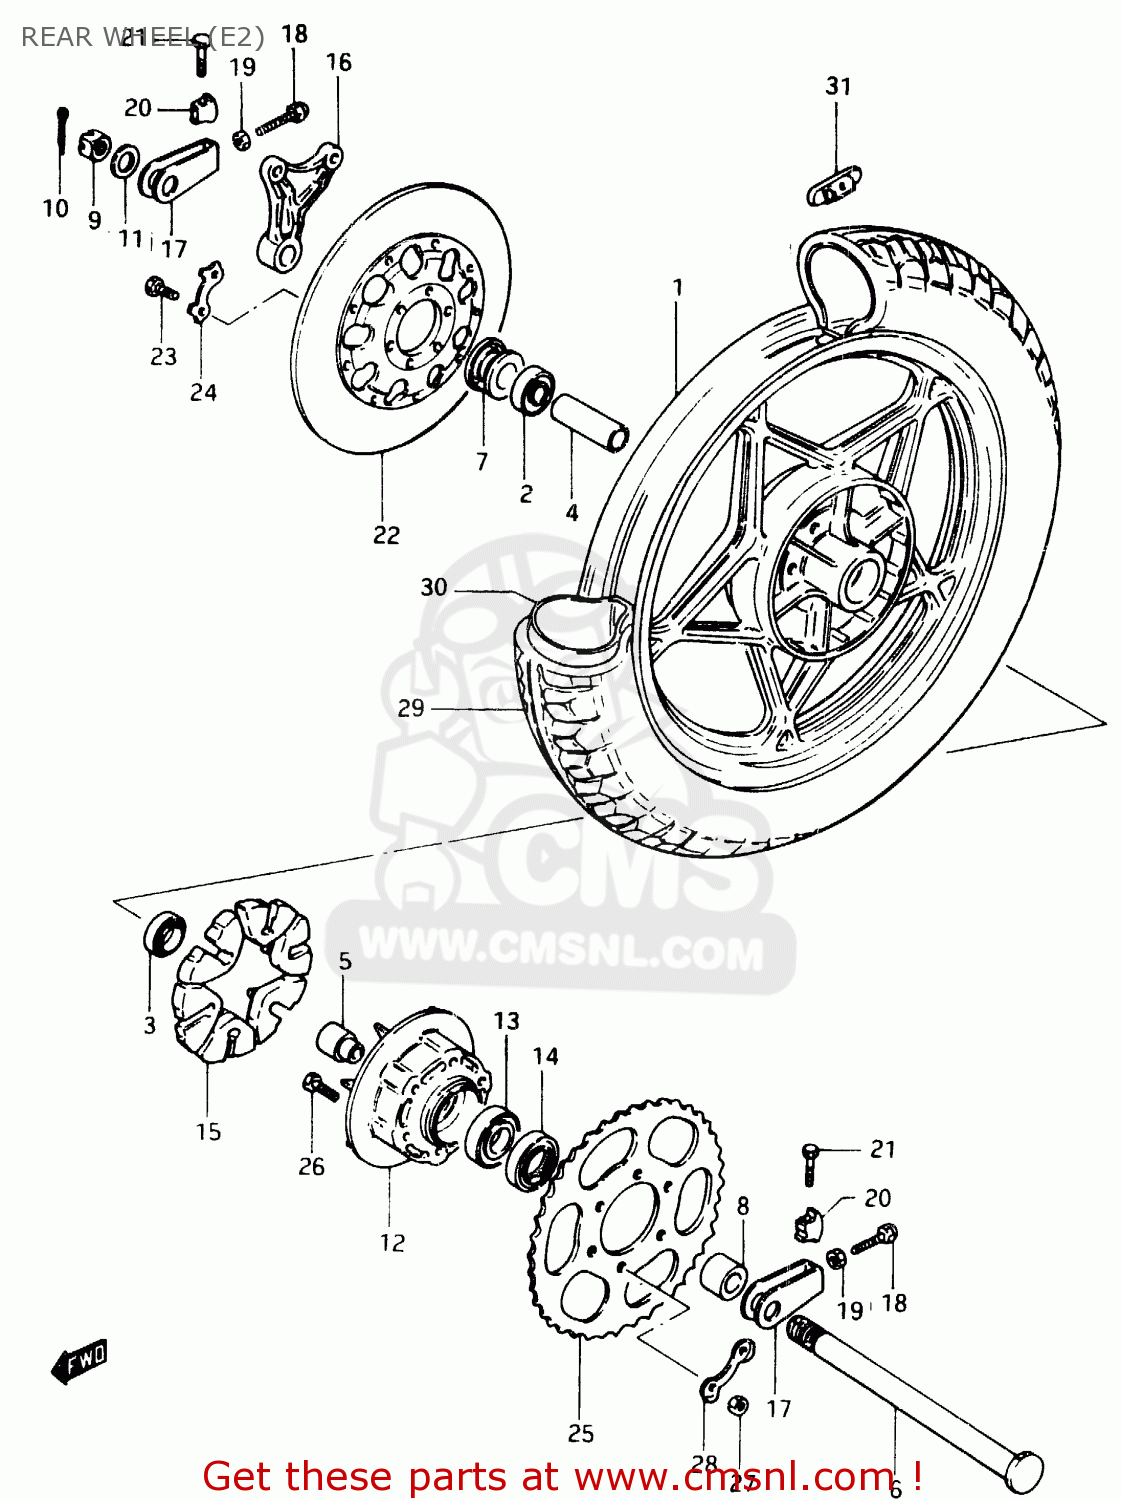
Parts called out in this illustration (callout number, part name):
1	WHEEL, REAR (18*MT*2.15)
2	BEARING
3	BEARING
4	SPACER, BEARING
5	SPACER,REAR HUB BEARING
6	AXLE, REAR
7	SPACER,REAR AXLE
8	SPACER(17X30.5X16.3)
9	NUT
10	PIN,COTTER
11	WASHER (17X30X3.2)
12	DRUM,REAR SPROCKET MOUNT
13	BEARING
14	SEAL,OIL(30.5X52X8)
15	ABSORBER,RR HUB SHOCK
16	BRACKET, REAR CALIPERS
17	ADJUSTER,CHAIN
18	BOLT 8X50
19	NUT
20	SUPPORTER,CHAIN ADJUST
21	BOLT
22	DISC, REAR BRAKE
23	BOLT(8X25)
24	WASHER
25	SPROCKET,REAR
26	BOLT
27	NUT
28	WASHER
29	TIRE (3.75S-18)
30	TUBE,INNER
31	BALANCER,WHEEL
